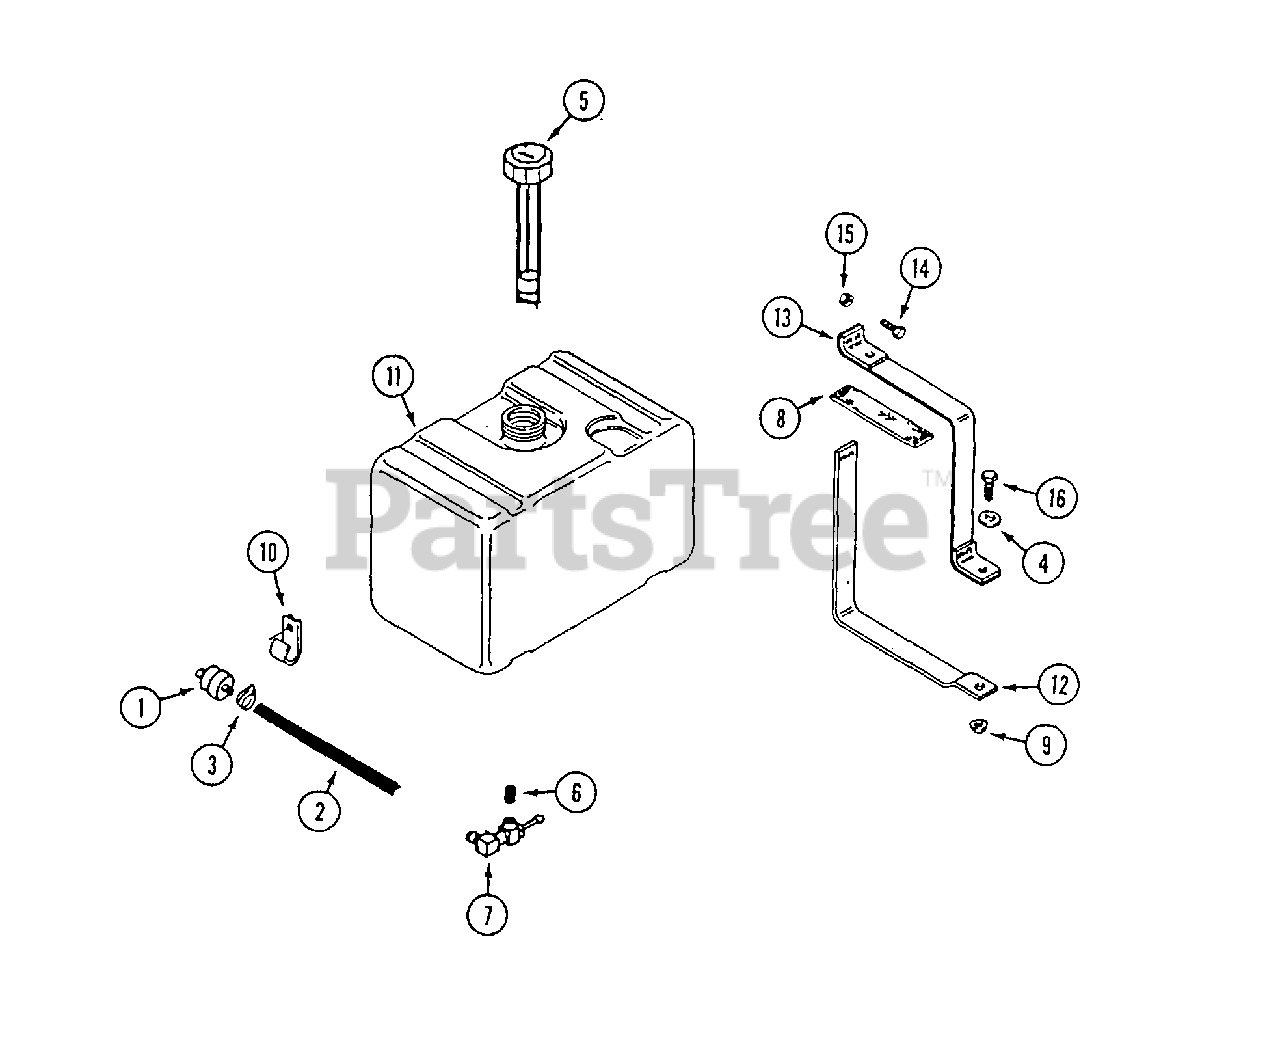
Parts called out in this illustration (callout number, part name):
1	FILTER - fuel
2	HOSE - fuel (cut to length)
4	WASHER - 5/16"
5	CAP - fuel tank (with gauge) 2-1/4"
6	NIPPLE - pipe 1/8"
7	VALVE - shut off
9	NUT - 5/16" - 18 flange lock
10	CLIP - "J" fuel line
11	TANK - fuel (2-1/4" filler tube) (plastic)
12	BRACKET - fuel tank
13	STRAP - fuel tank
14	BOLT - 1/4" - 20 x 1-1/4"
15	NUT - 1/4" - 20 lock
16	BOLT - 5/16" - 18 x 1"
